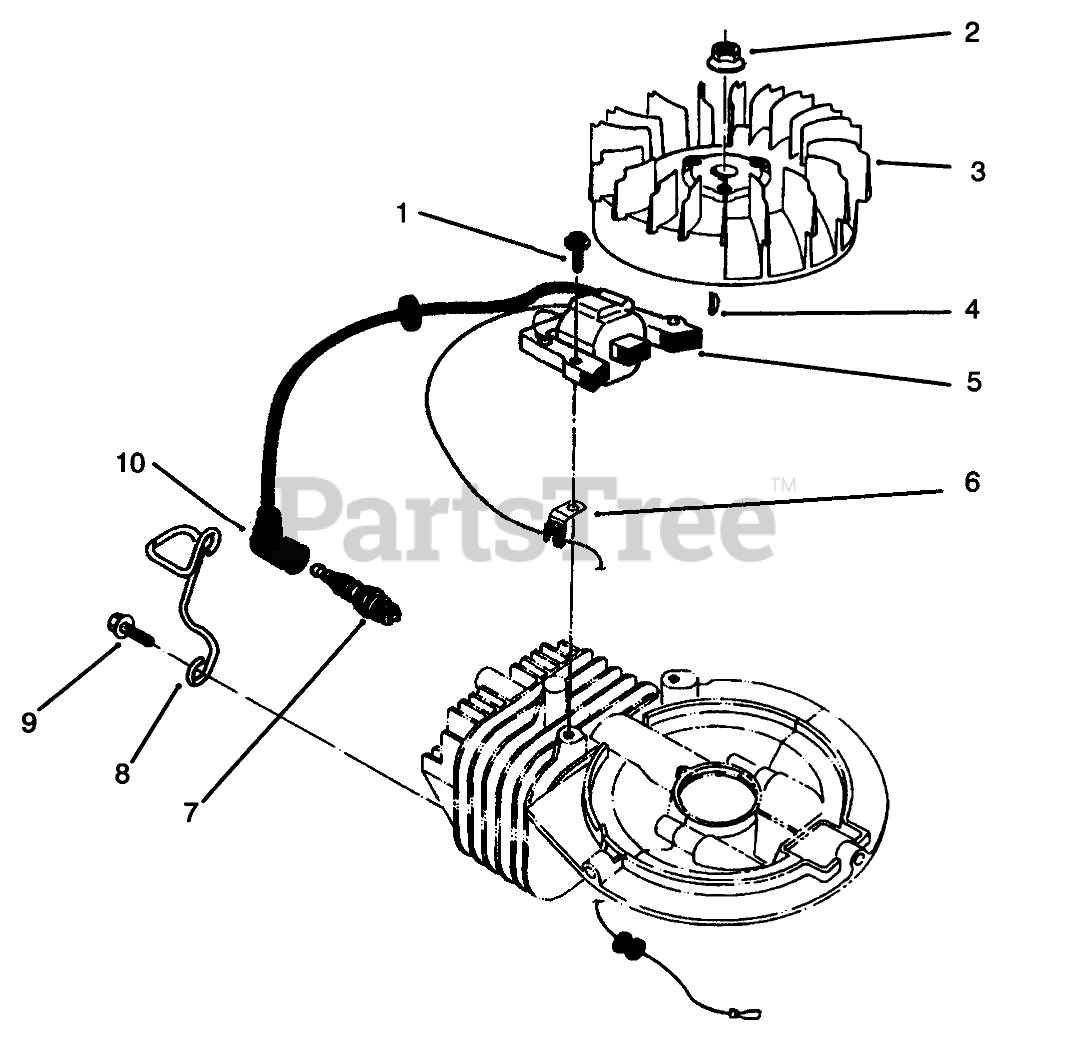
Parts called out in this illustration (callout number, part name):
1	SCREW
3	FLYWHEEL
5	COIL-MAGNETO
6	CLAMP
7	Sparkplug
8	PROTECTOR-PLUG
9	SCREW
10	CAP-SPARKPLUG
